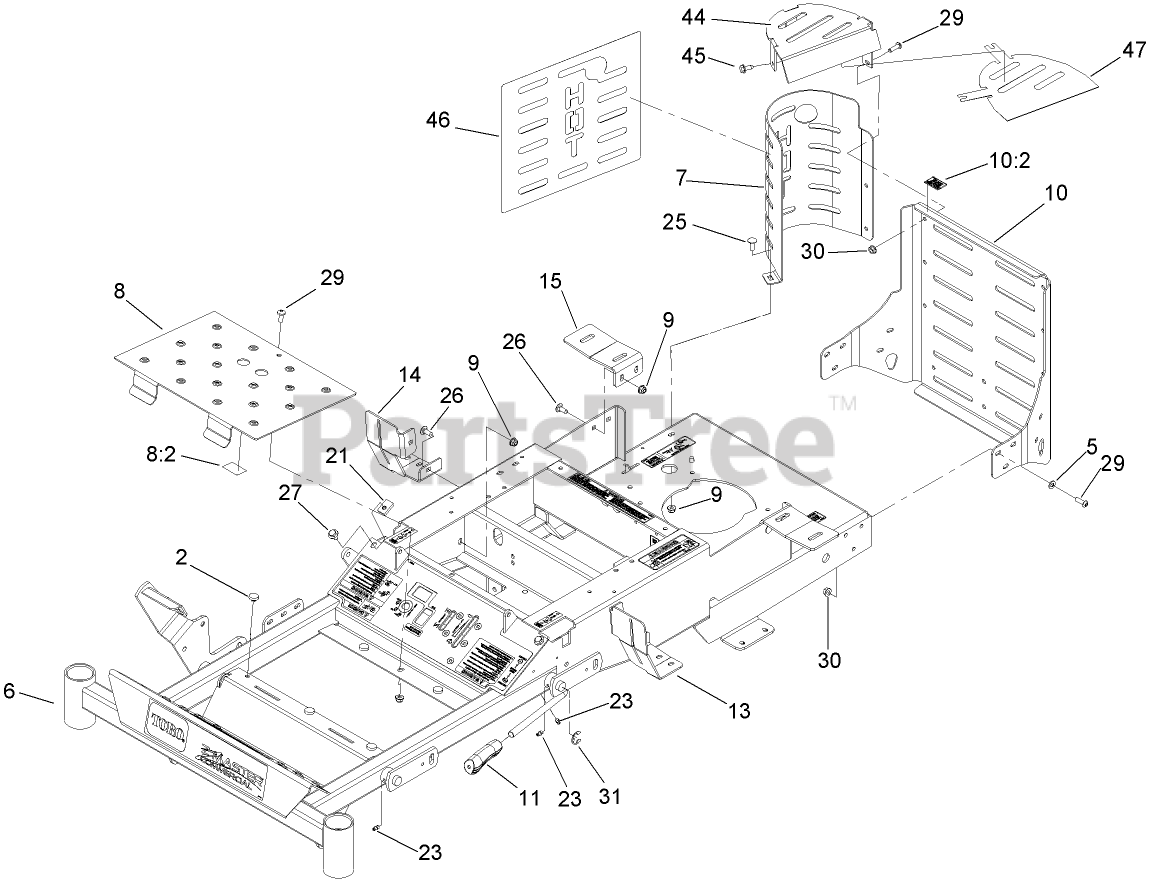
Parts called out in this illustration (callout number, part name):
2	BUMPER
5	WASHER-PLAIN
6	FRAME ASM W/DECALS, CE
7	GUARD-MUFFLER
8	FLOOR PAN ASM
8:2	DECAL-WARNING
9	NUT-HF, NI
10	REAR GUARD ASM
10:2	DECAL-SURFACE, HOT
11	GRIP-LEVER, BRAKE
13	MOUNT-TANK, FUEL (LH)
14	MOUNT-TANK, FUEL (RH)
15	BRACKET-FUEL TANK, REAR
21	STOP-MOTION
23	FITTING-GREASE
25	SCREW-CARR
26	SCREW-CARR
27	SCREW-HHF
29	SCREW-HSBH
30	NUT-HF
31	E-RING
44	SHIELD-HEAT
45	SCREW-HWHTF
46	GUARD-FOIL
47	SHIELD-FOIL
